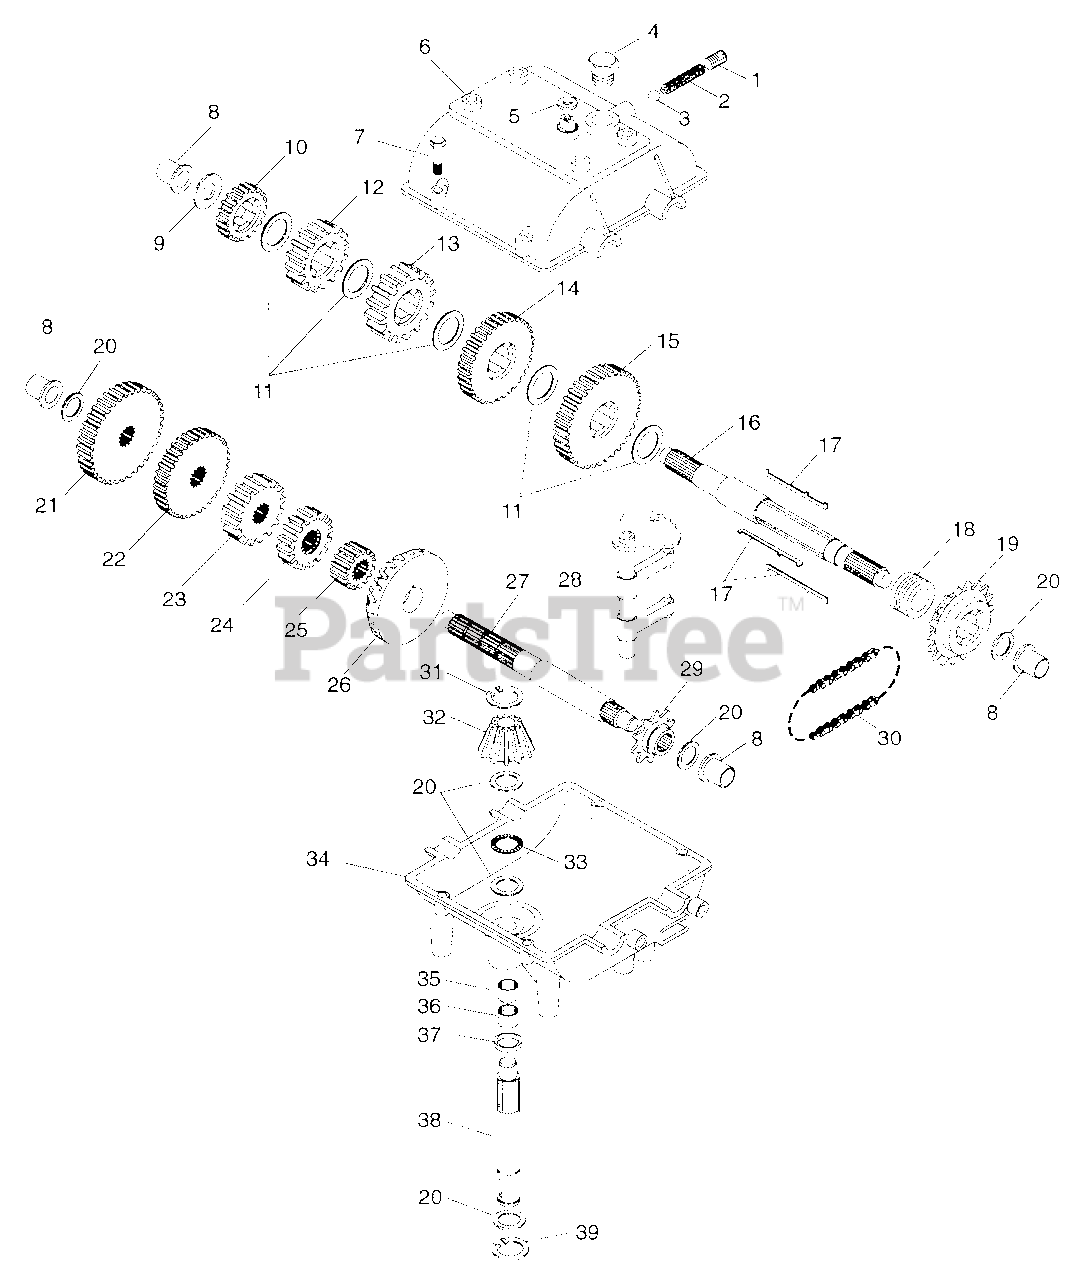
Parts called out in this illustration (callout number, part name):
1	Screw, Set 3/8-16 x 3/8
3	Ball, Steel 5/16
4	Plug, Threaded
5	Seal, Square Cut
6	Cover, Transmission
7	Screw, HHD Taptite, 1/4-20 x 1.25
8	Bushing, Flanged
9	Washer, Thrust
10	Gear, Spur(27 Teeth)
11	Washer, Thrust
12	Gear, Spur(30 Teeth)
13	Gear, Spur(32 Teeth)
14	Gear, Spur(35 Teeth)
15	Gear, Spur(37 Teeth)
16	Shaft, Output & Brake
18	Collar, Shift
19	Sprocket(18 Teeth)
20	Washer, Thrust
21	Gear, Spur(23 Teeth)
22	Gear, Spur(20 Teeth)
23	Gear, Spur(18 Teeth)
24	Gear, Spur(15 Teeth)
25	Gear, Spur(12 Teeth)
26	Gear, Bevel(42 Teeth)
27	Shaft, Counter
28	Rod & Fork Assembly, Shift
29	Sprocket(9 Teeth)
30	Chain, Roller(No. 41 Chain, 24 Links)
31	Ring, Retaining
32	Bevel Pinion, Input
33	Bearing, Thrust
34	Case, Transmission
35	Bearing, Needle
36	Bearing, Needle
38	Shaft, Input
39	Ring, Retaining
